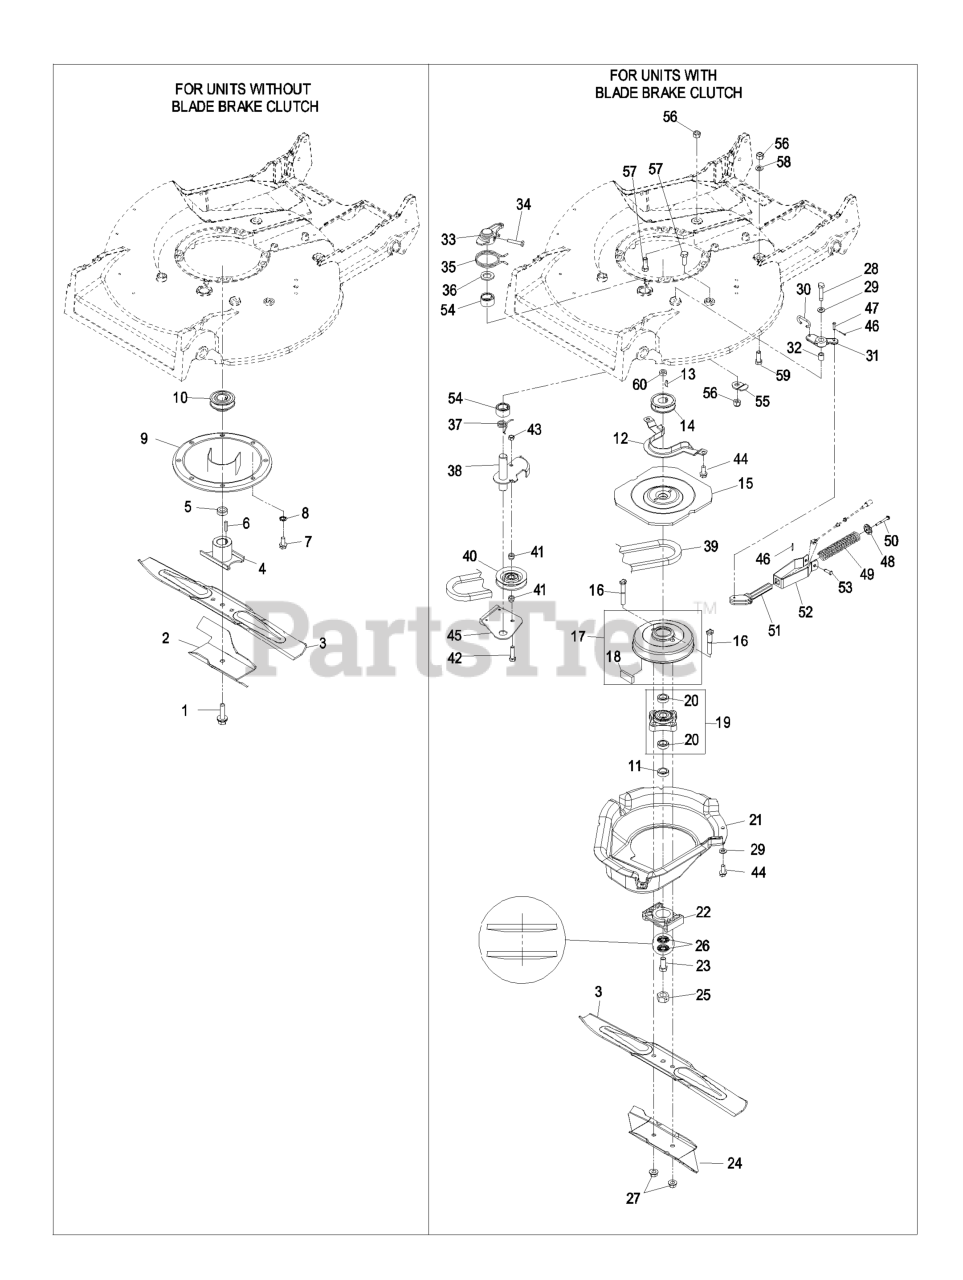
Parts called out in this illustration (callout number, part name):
2	STIFFENER-BLADE
3	BLADE-BAGGING, 21 INCH
4	RETAINER-BLADE
5	SPACER-RETAINER, BLADE
6	KEY-SQUARE
7	Screw-HWH 5/16-18 X 3/4 Tf
8	WASHER-LOCK, INTERNAL
9	PROTECTOR-CRANKSHAFT
10	PULLEY-DRIVER
11	SPACER-SHAFT, OUTPUT
12	BRACKET-GUIDE, BELT
13	KEY-WOODRUFF
14	PULLEY-DRIVER
15	FLYWHEEL-BBC
16	BOLT-BLADE
17	BRAKE DRUM ASM
18	DAMPENER-VIBRATION
19	HUB ASM
22	SPACER-BLADE
23	SCREW-HH
24	STIFFENER-BLADE
25	NUT-BLADE
26	WASHER-SPRING
27	Nut, Hex 3/8-24 Lock
28	SCREW-HH
29	WASHER-PLAIN
30	LINK-CONTROL
31	BELLCRANK
32	SLEEVE-BELLCRANK
34	SCREW-HH
35	SPRING-TORSION
37	SPRING-TORSION
38	ARM-IDLER
39	V-BELTNSP
41	SPACER-PULLEY, IDLER
42	SCREW-HH
43	NUT-LOCK, NI
44	Screw-HWH 5/16-18 X 3/4 Tf
46	PIN-COTTER
47	PIN-SPRING
48	RETAINER-SPRING
50	SCREW-HWHTF
51	GUIDE-SPRING
52	BRACKET-SPRING
53	PIN-CABLE
54	BEARING
55	SHIELD-RETAINER
56	NUT-LOCK, NI
57	SCREW-HH
58	WASHER-HARDENED
59	SCREW-HH
60	SPACER-PULLEY
